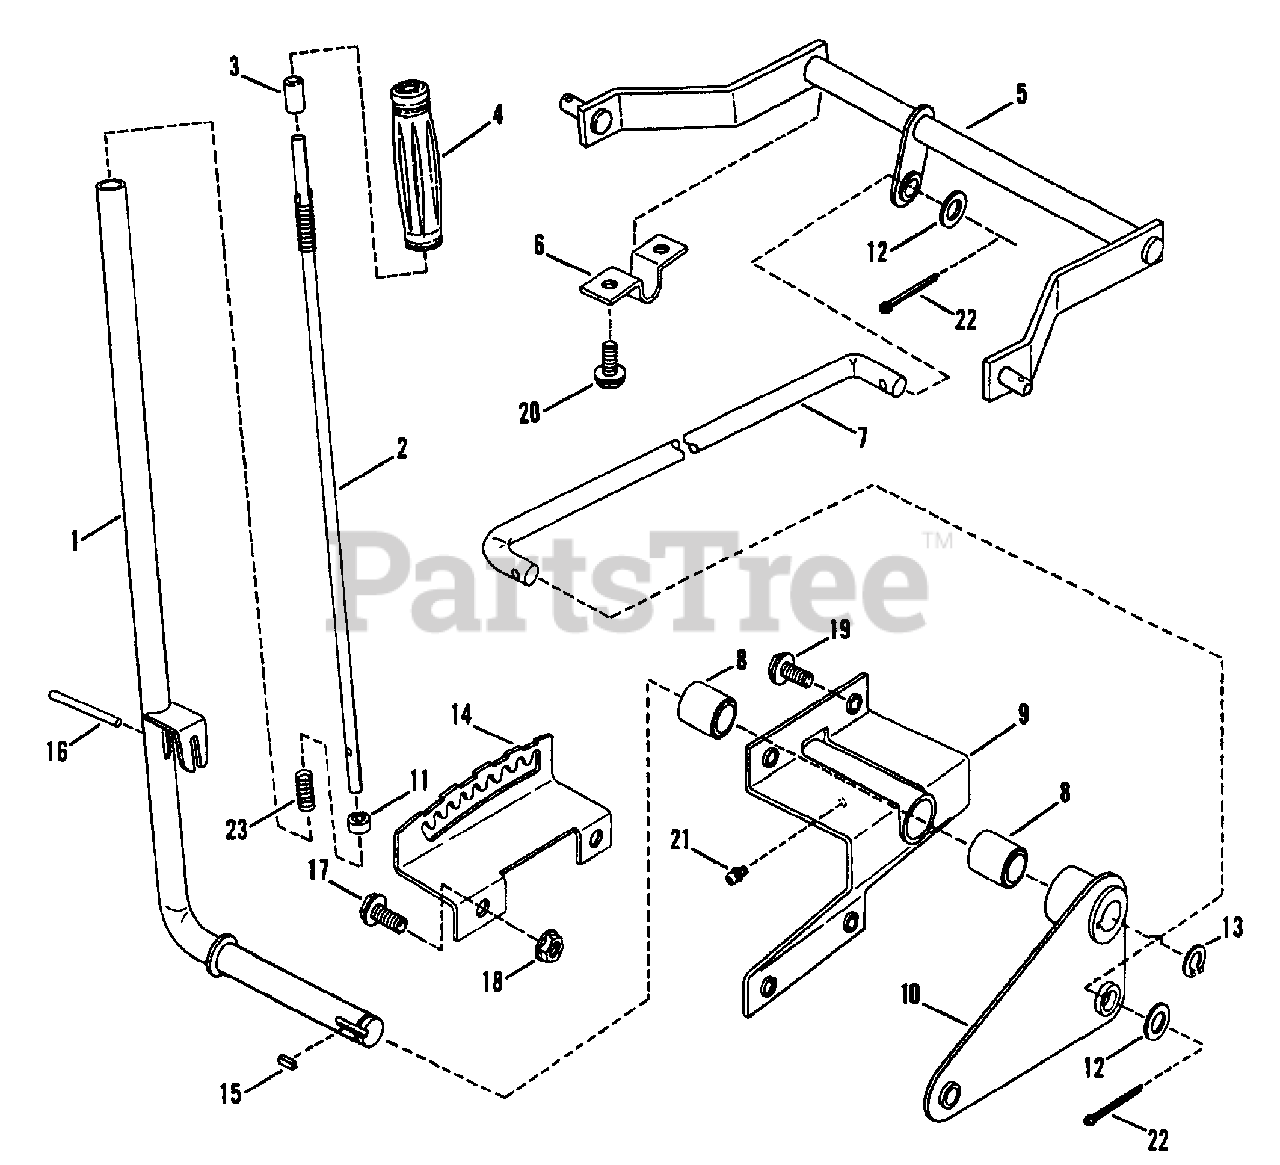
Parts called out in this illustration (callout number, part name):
1	ARM, Implement Lift Lever
2	ROD, Lift Lever
3	CAP, Lift Release
4	GRIP, Handle
5	ARM, Rear Lift (1985)(22")
6	BRACKET, Hanger
7	LIFT-ROD
8	BEARING, Sleeve
9	PIVOT ASSY, Lift Lever
10	LEVER-ARM
11	PLUG, Rod
12	WASHER, 1/2 SAE
13	RING, 7/8" Ext. Retaining
14	QUADRANT, Lift Lever
15	KEY, 1/4 x 1/4 Square
16	PIN, 3/16 x 2" Groove
17	BOLT, 3/8-16 x 3/4" Hex Flange Lock
18	NUT, 3/8-16 Hex Flange Lock
19	SCREW, 5/16-18 x 5/8" Hex Washer Face Self-Tap
20	SCREW, 3/8-16 x 1/2" Hex Washer Face Self-Tap
21	LUBE FITTING, Straight (press-fit for .187 dia. Hole)
22	PIN, 1/8 x 1" Cotter
23	SPRING, Lift Handle
